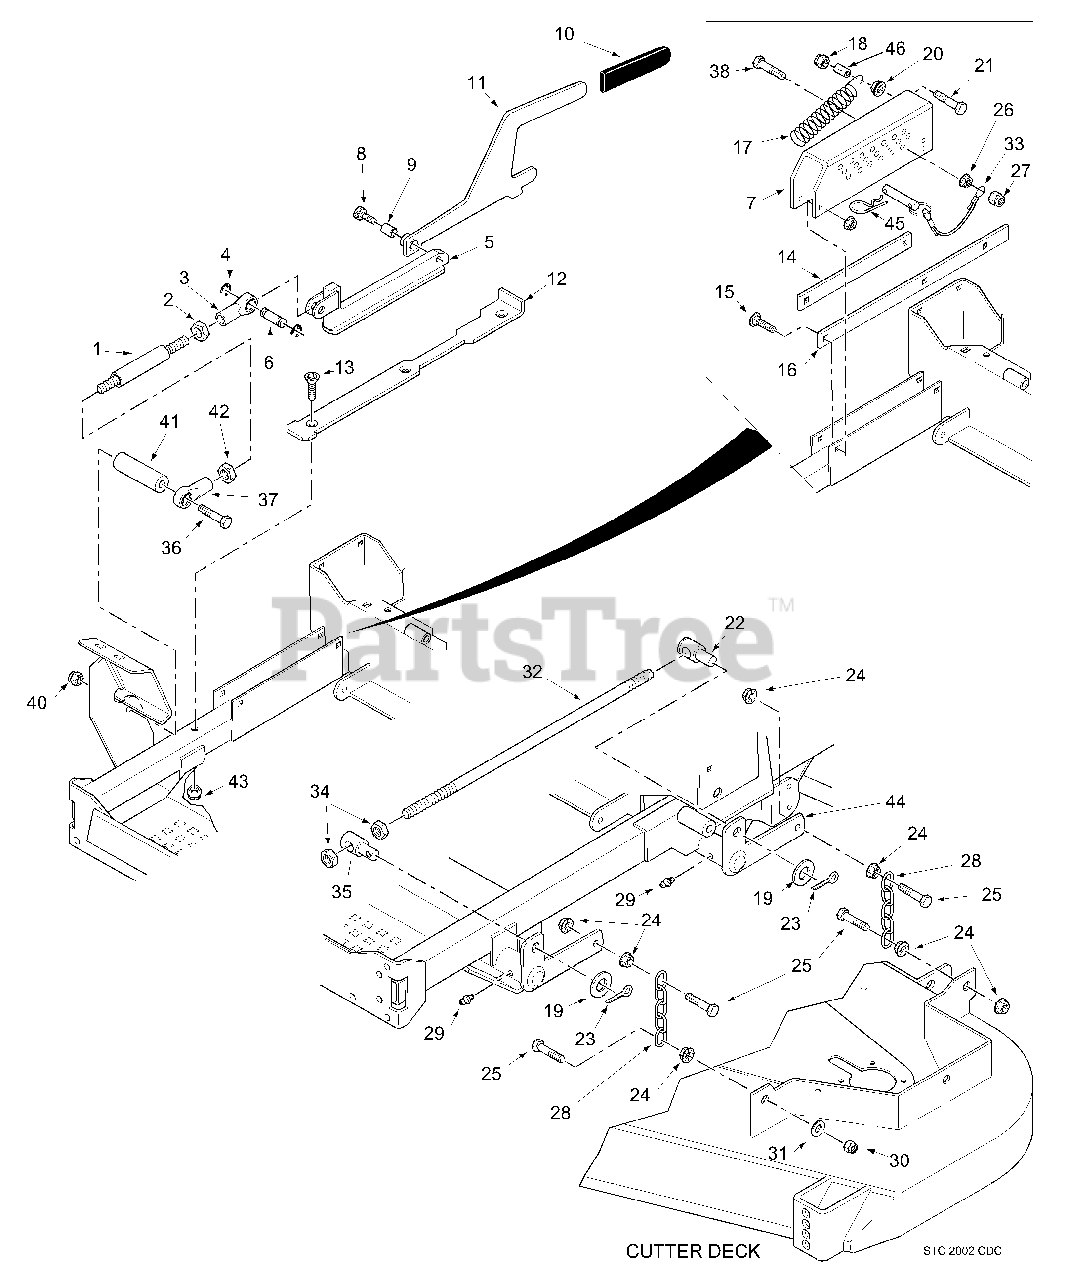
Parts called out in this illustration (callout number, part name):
1	Rod, Deck Lift Linkage
2	Nut, Jam 1/2-20 LH Thread
3	Rod End, 1/2-20 Female Thread
4	Retaining Ring, 1/2" External "E"
5	Slide, Deck Height Adjust
6	Pin, Deck Lift
7	Bracket, Cutting Height Adjustment
8	Bolt, Shoulder 1/2-3/4"
9	Bushing .502 ID
10	Grip, Deck Latch Lever
11	Lever, Deck Latch
12	Slide, Cutting Height
13	Screw, Cap 5/16-18 x 3" FHHS
14	Guide, Short
15	Bolt, Carriage 5/16-18 x 1"
16	Guide, Long
17	Spring, Helper
18	Nut, 3/8-16 Center Lock
19	Flatwasher, 5/8-.656 x 1.312 x .095
20	Nut, 3/8-16 Serr. Flange
21	Bolt, Hex Head 3/8-16 x 1-1/4"
22	Swivel Joint LH
23	Cotter Pin, 3/16 x 1"
24	Nut, Serr. Flange 3/8-16
25	Bolt, Hex Head 3/8-16 x 1-1/2"
26	Nut, Serr. Flange 3/8-16
27	Nut, Elastic Stop 3/8-16
28	Chain
29	Grease Fitting, 1/4-28 Self Tap
30	Nut, Elastic Stop 3/8-16
31	Flatwasher, 3/8-.391 x .938 x .105
32	Stud, 1/2-13 x 20"
33	Lanyard Pin
34	Nut, 5/8-11 UNC
35	Swivel Joint RH
36	Bolt, Hex Head 1/2-13 x 5"
37	Rod End, 1/2-20 Female RH Thread
38	Bolt, Hex Head 3/8-16 x 3-1/2"
40	Lock Nut, 1/4-20
41	Spacer
42	Nut, 1/2-20 UNF-2B
43	Nut, Elastic Stop 5/16-18
44	Lift Bellcrank Weldment, LH Rear
45	Hair Pin Cotter, .177 x 3-1/4"
